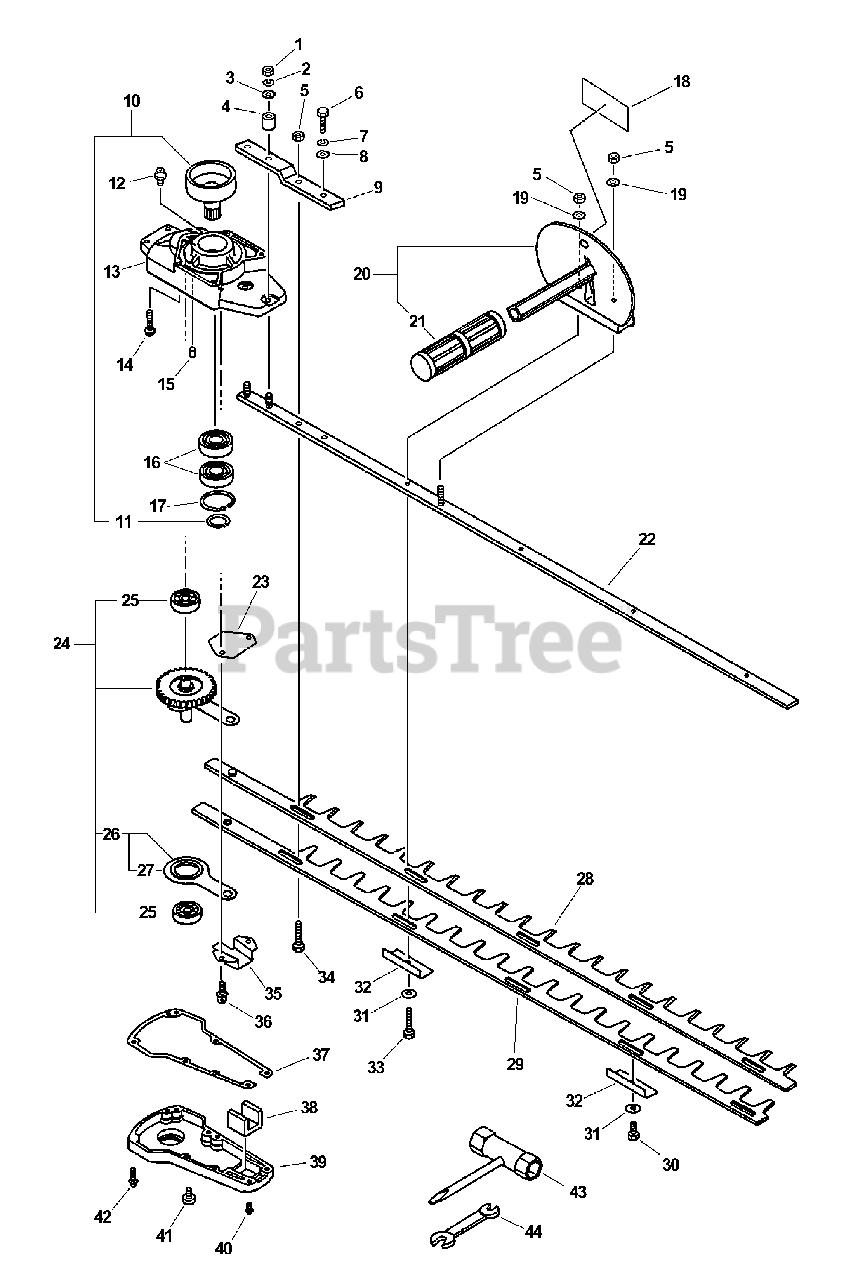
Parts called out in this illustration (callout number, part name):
1	NUT, HEX M6
2	WASHER, SPRING 6
3	WASHER 6.5×11.5×0.8
4	SPACER
5	NUT M6
6	BOLT 6×10
7	WASHER, SPRING 6
8	WASHER 6.5×11.5×0.8
9	BRACKET, BLADE
10	DRUM, CLUTCH
11	RING, RETAINING - 16
12	FITTING, GREASE
13	CASE, GEAR
14	BOLT 5×30
15	PIN, LOCATING 4
16	BEARING, BALL 6003
17	RING, SNAP 35
18	LABEL, CAUTION
19	WASHER 6.5×13×1
20	BRACKET ASSY
22	BAR, FRAME
23	GUIDE
23	PLATE, GUIDE
24	GEAR ASSY
24	GEAR SHAFT ASSY
25	BEARING, BALL 6200
26	CONROD ASSY
27	BEARING, NEEDLE
28	BLADE - UPPER
29	BLADE - LOWER
30	BOLT 6×22
31	WASHER
32	INSULATOR
33	BOLT 6×40
34	BOLT 6×25
35	GUIDE
35	GUIDE, BLADE
36	BOLT 5×14
37	GASKET, GEAR CASE
39	LID, GEAR CASE
40	SCREW 4×14
41	BOLT 8×8 SP
42	SCREW 4×22
43	T-WRENCH 13×19×180
44	SPANNER 8×10
